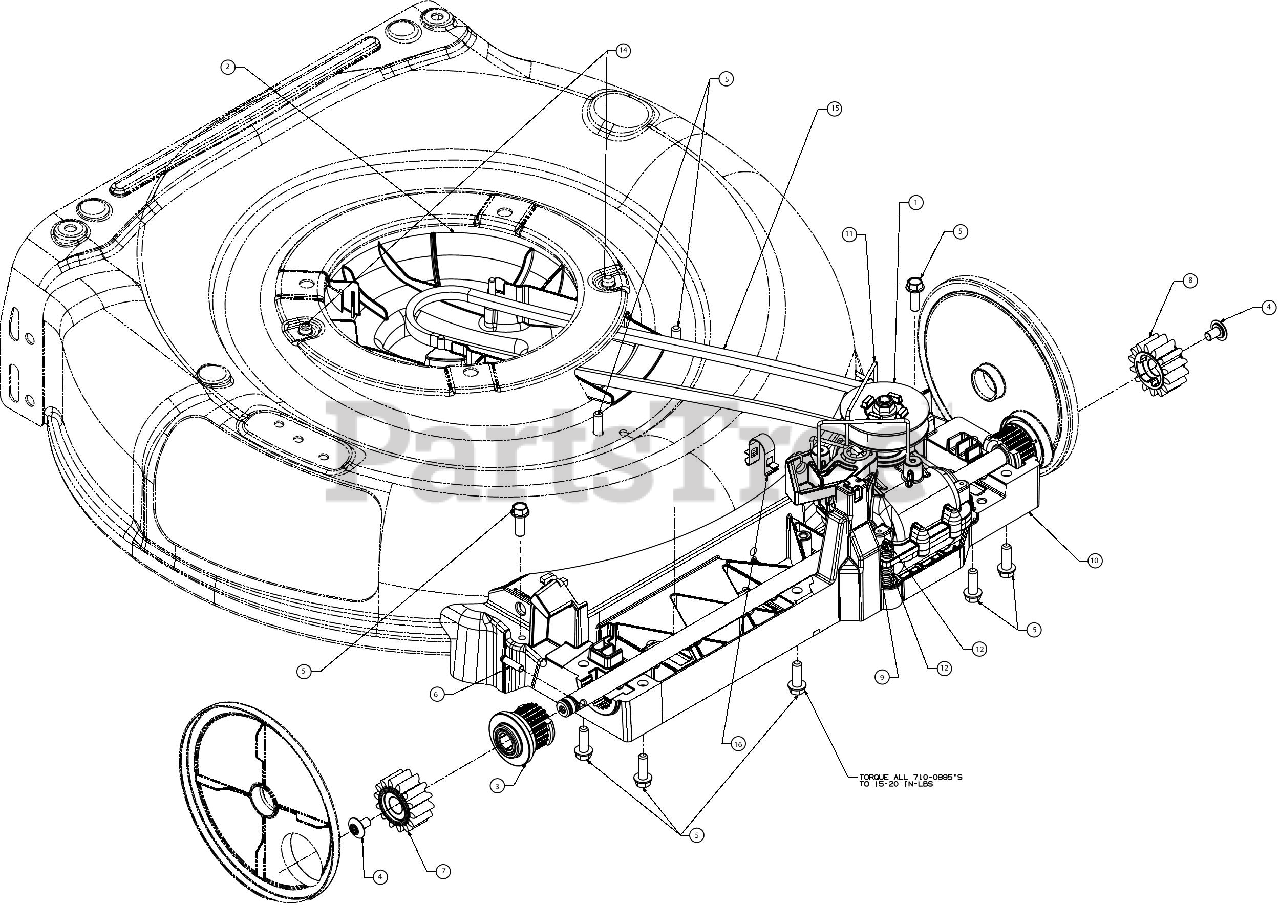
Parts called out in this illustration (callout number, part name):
1	FORWARD TRANSMISSION ASSEMBLY
2	ENGINE BAFFLE ASSEMBLY
3	SPHERICAL BEARING ASSEMBLY
4	SCREW 1/4-20 X .39
5	SCREW 1/4-15 X .750
7	SPUR GEAR 14T R
8	SPUR GEAR 14T L
9	SPRING COMPRESSION
10	LOWER TRAY
11	TRANSMISSION WIRE
12	COMPRESSION SPRING
14	SHOULDER SCREW 1/4-20 X .50
15	V-BELT 3L X 34.18
15	Cub Cadet TRANSMISSION BELT
15	Genuine Factory Parts TRANSMISSION BELT
16	FRONT AXLE CLIP
